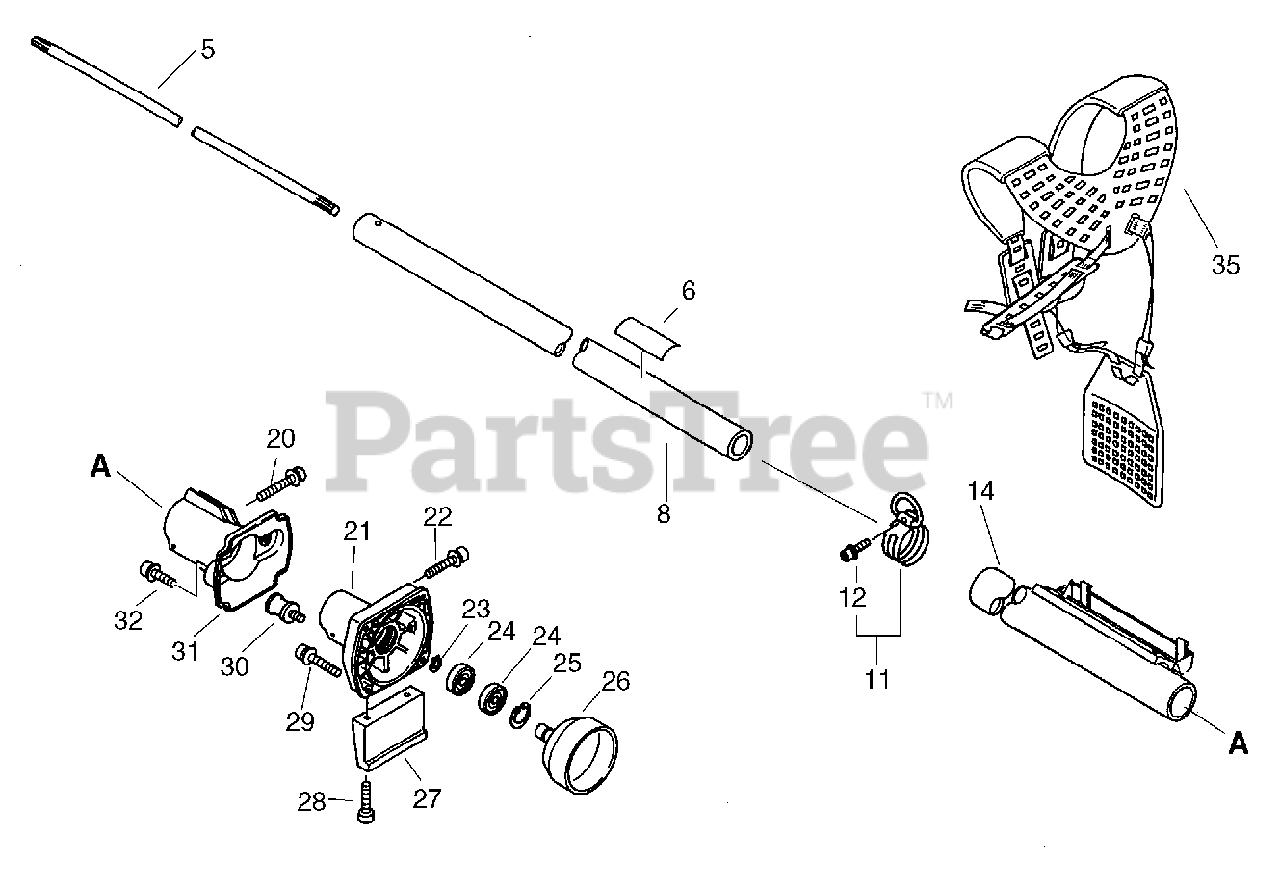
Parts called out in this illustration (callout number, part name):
5	DRIVESHAFT
6	LABEL - CAUTION
8	PIPE, MAIN
11	HANGER KIT
12	SCREW - 5X20
14	PIPE ASSY
20	SCREW - 5X35
22	SCREW - 5X30
23	RING, RETAINING - 15
24	BEARING, BALL - 6202
25	RING, RETAINING - 35
26	DRUM, CLUTCH
28	SCREW - 5X20
29	SCREW - 5X25
31	CLAMP, MAIN PIPE
32	SCREW - 5X14
35	HARNESS, SHOULDER
